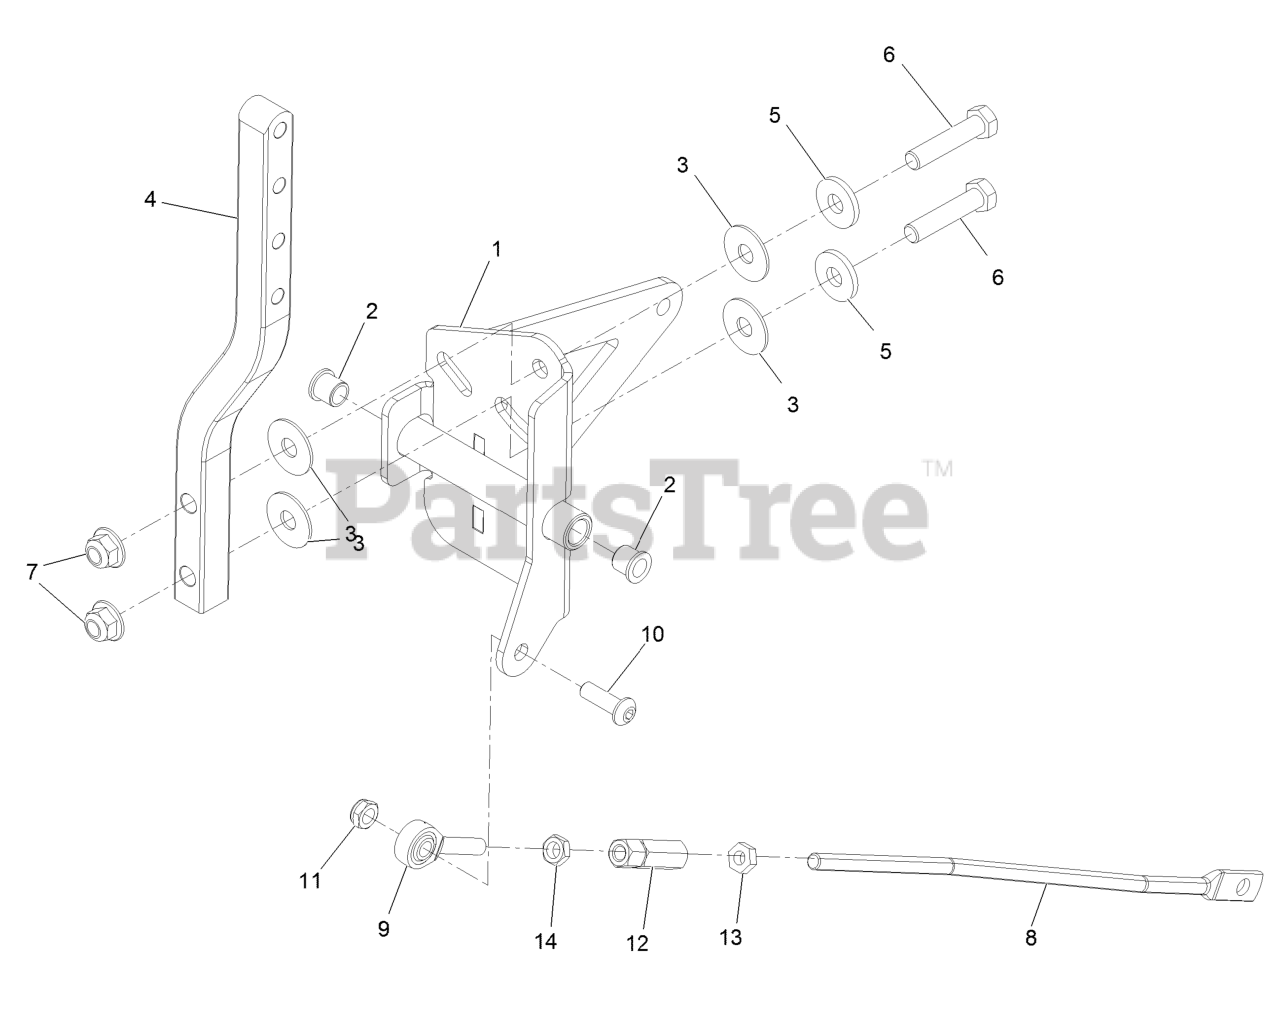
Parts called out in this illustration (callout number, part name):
1	LH CONTROL PIVOT ASM
2	BEARING
3	WASHER-PLASTIC
4	ARM-MOTION CONTROL
5	WASHER
6	SCREW-HH
7	NUT-HF, NI
8	LINK,MOTION CONTROL
9	BEARING-ROD END, LH
10	SCREW-HSBH
11	NUT-LOCK, NI
12	NUT-ROD ADJUSTMENT
13	NUT-JAM
14	NUT-JAM
